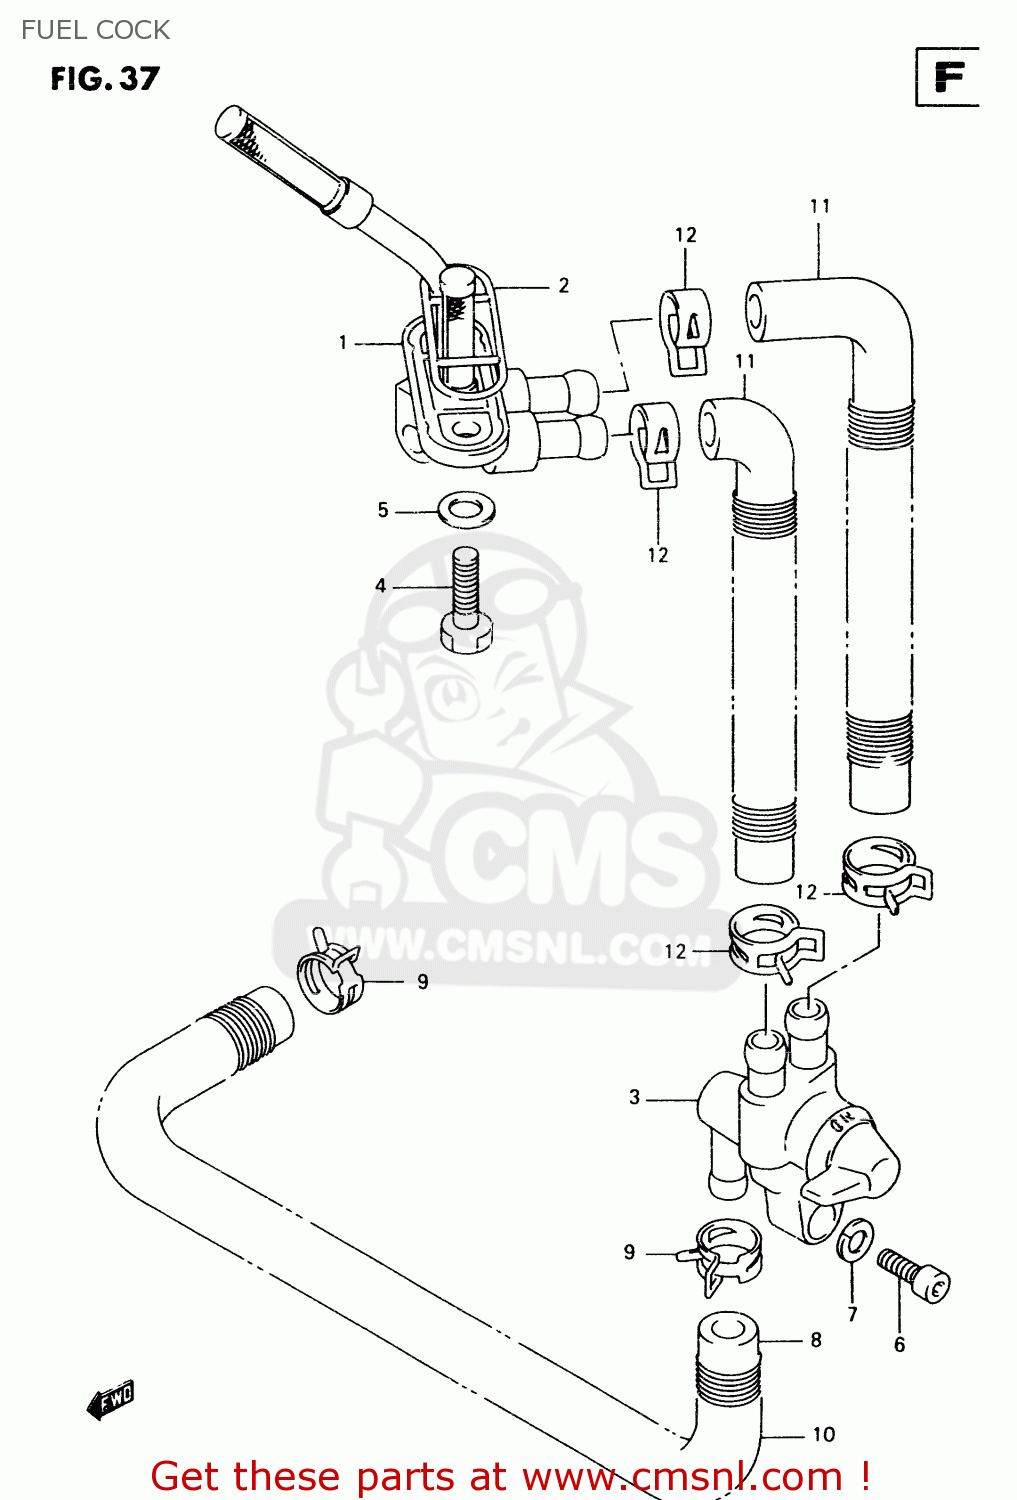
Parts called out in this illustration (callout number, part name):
1	FILTER UNIT,FUEL
2	GASKET,JOINT (NAS)
3	COCK ASSY,FUEL
4	BOLT(6X20)
5	GASKET(6.4X11.5X0.8) (NAS)
6	BOLT
7	LOCK,WASHER
8	HOSE,FUEL
9	CLIP
10	SPRING
11	HOSE,FUEL FILTER/COCK
12	CLIP
